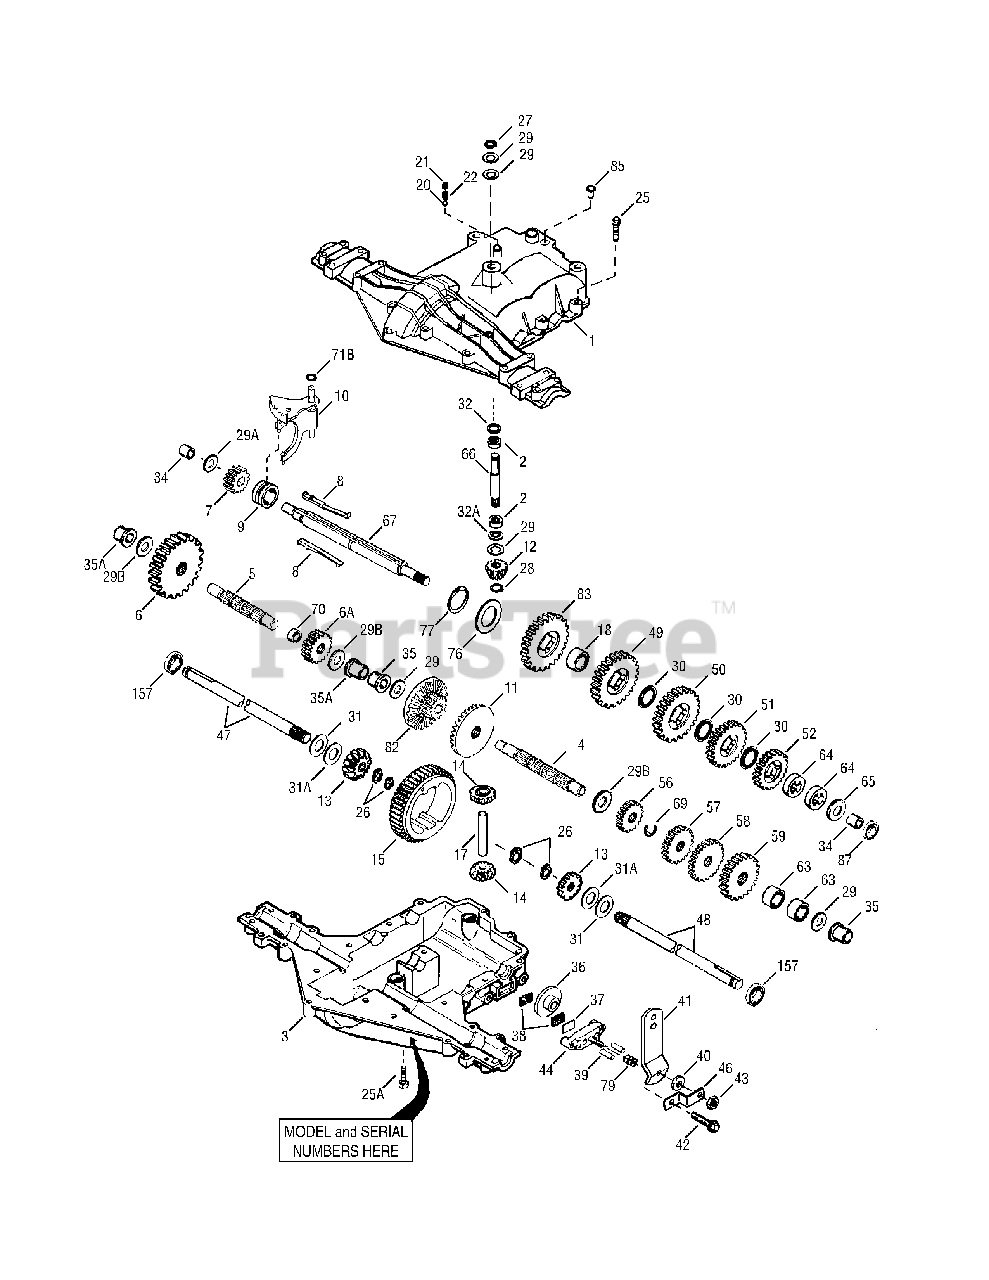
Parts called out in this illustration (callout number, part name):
1	Transaxle Cover
2	Needle Bearing (¹/2" long)
3	Transaxle Case
4	Countershaft
5	Output Shaft
6	Spur Gear (38T-PM/SER)
6A	Spur Gear (15T-PM/SER)
7	Spur Gear (11T-PM/SER)
8	Shift Key Set (Qty. 2)
9	Shift Collar
10	Shift Rod & Fork Assembly
11	Bevel Gear (30T-PM)
12	Input Bevel Pinion (13T-PM)
13	Bevel Gear 13T (Incl. ref. 13 & 14)
14	Bevel Gear 13T (Incl. ref. 13 & 14)
15	Ring Gear (43T)
17	Drive Pin
18	Spacer (1.130" x .695")
20	Ball (Stainless Steel 5/16" dia.)
21	Screw, 3/8-16 x 3/8"
22	Spring
25	Screw, 1/4-20 x 1-1/4"
25A	Screw, 1/4-20 x 1-3/8"
26	Retaining Ring-package of 2
27	Retaining Ring
28	Retaining Ring
29	Washer .627" ID .031"
29A	Thrust Washer (.563" ID x .031")
29B	Thrust Washer (.762" ID X .031")
30	Shift Washer (Cupped)
31	Washer .750" ID .56"
31A	Washer .750" ID .062
32	Oil Seal 5/8"
32A	O Ring (.823" OD)
34	Bushing (.563")
35	Flanged Bushing (.625" ID)
35A	Flanged Bushing (.751" ID)
36	Brake Disk
37	Brake Pad Plate
38	Brake Pad (pkg. of 2)
39	Dowel Pin .3125" x .750"
40	Washer .312" ID .059"
41	Brake Lever
42	Screw 1/4-20 x 1-3/8"
43	Lock Nut 5/16-24
44	Brake Pad Holder
46	Bracket
47	Axle (10.719" long) (Incl. 26)
48	Axle (15.312" long) (Incl. 26)
49	Spur Gear (27T-PM/IC)
50	Spur Gear (22T-PM/IC)
51	Spur Gear (19T-PM/IC)
52	Spur Gear (16T-PM/IC)
56	Spur Gear (13T-PM/SER)
57	Spur Gear (18T-PM/SER)
58	Spur Gear (21T-PM/SER)
59	Spur Gear (24T-PM/SER)
63	Countershaft Spacer 1-1/8" x 3/8’’
64	Brake Shaft Spacer 1-3/8" x 3/8’’
65	Washer .563" ID .062
66	Input Shaft
67	Brake Shaft
69	Retaining Ring (.75" x .042")
70	Spacer (.890")
71B	O-Ring
76	Flat Washer (1.128" ID x .058")
77	Retaining Ring (1.125" x .050")
79	Spring
82	Bevel (30T) & Spur Gear
83	Spur Gear (27T-PM/IC)
85	Oil Fill Plug
87	Oil Seal 9/16" ID
157	Oil Seal 3/4" ID
